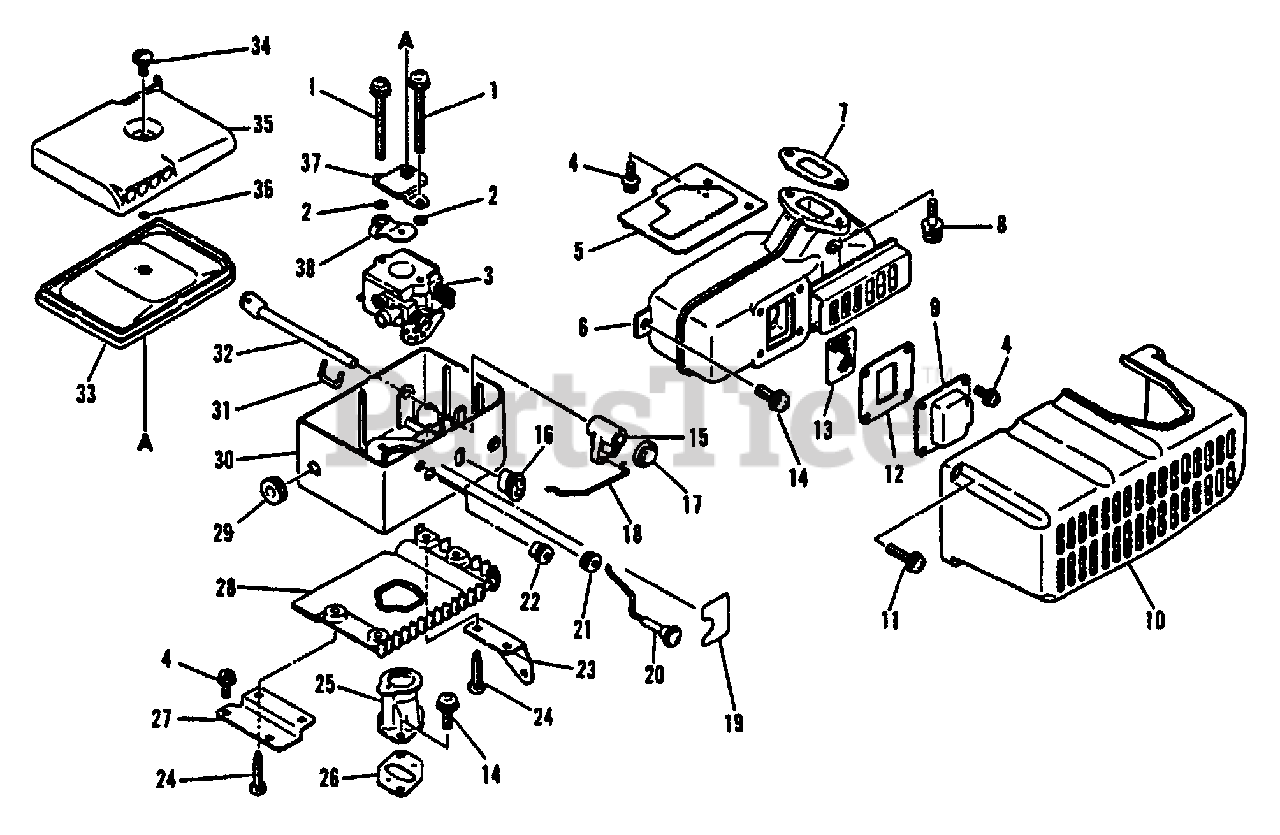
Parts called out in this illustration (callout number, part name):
1	SCREW 5×45
2	WASHER 5.2×8×0.8T
3	CARBURETOR - WA-157
4	SCREW 4×10
5	INSULATOR
6	MUFFLER
7	GASKET, MUFFLER
8	BOLT 5×16
9	LID, MUFFLER
10	COVER, EXHAUST
11	SCREW 5×20
12	GASKET, EXHAUST
13	SCREEN, SPARK ARRESTER
14	SCREW 5×14
15	ARM, THROTTLE LEVER
16	GROMMET
17	HOLDER, THROTTLE LEVER
18	ROD, THROTTLE
19	LABEL
20	ROD, CHOKE
22	GROMMET
24	SCREW 5×25
25	ADAPTER, INTAKE
28	INSULATOR
30	CASE, CARBURETOR
31	CONNECTOR, THROTTLE
32	SHAFT, THROTTLE
33	FILTER, AIR
35	COVER, AIR FILTER
36	O-RING 3
37	BRACKET, AIR FILTER
38	SHUTTER, CHOKE
